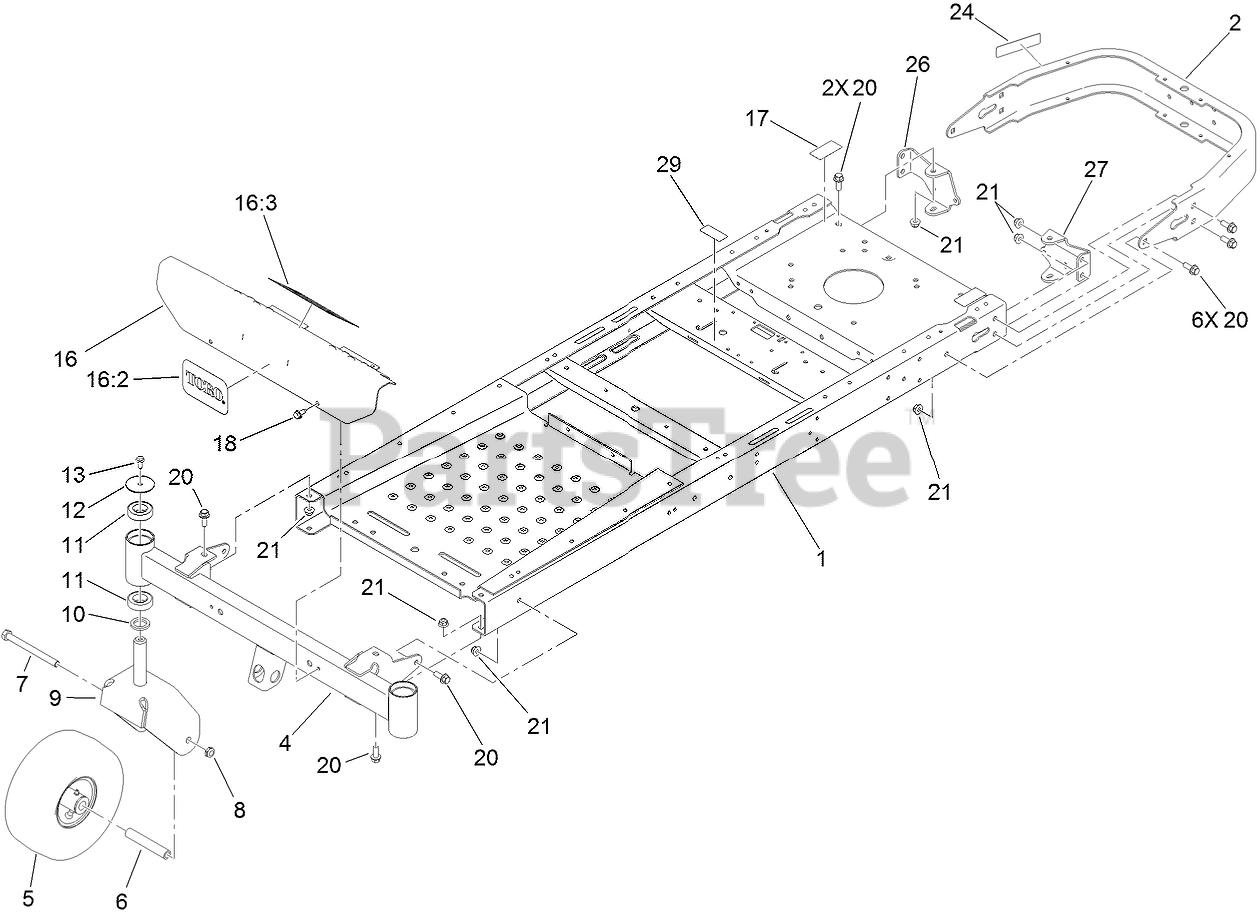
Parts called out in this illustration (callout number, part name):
2	BUMPER-REAR
4	AXLE-FRONT
5	CASTER WHEEL ASM (Cst)
6	BUSHING-SPANNER
7	SCREW-HH
8	NUT-LOCK, NI
9	FORK-CASTER
10	WASHER-THRUST
11	BEARING-BALL
12	WASHER
13	SCREW-HHF
16	FOOTREST ASM
16:3	DECAL-DANGER
17	DECAL-BYPASS
18	SCREW-HWHTF
20	SCREW-HHF
21	NUT-HF, NI
24	DECAL-ARRESTER, SPARK
26	MOUNT-HYDRO, REAR (RH)
27	MOUNT-HYDRO, REAR (LH)
29	DECAL-LOCATION, SERVICE DEALER
